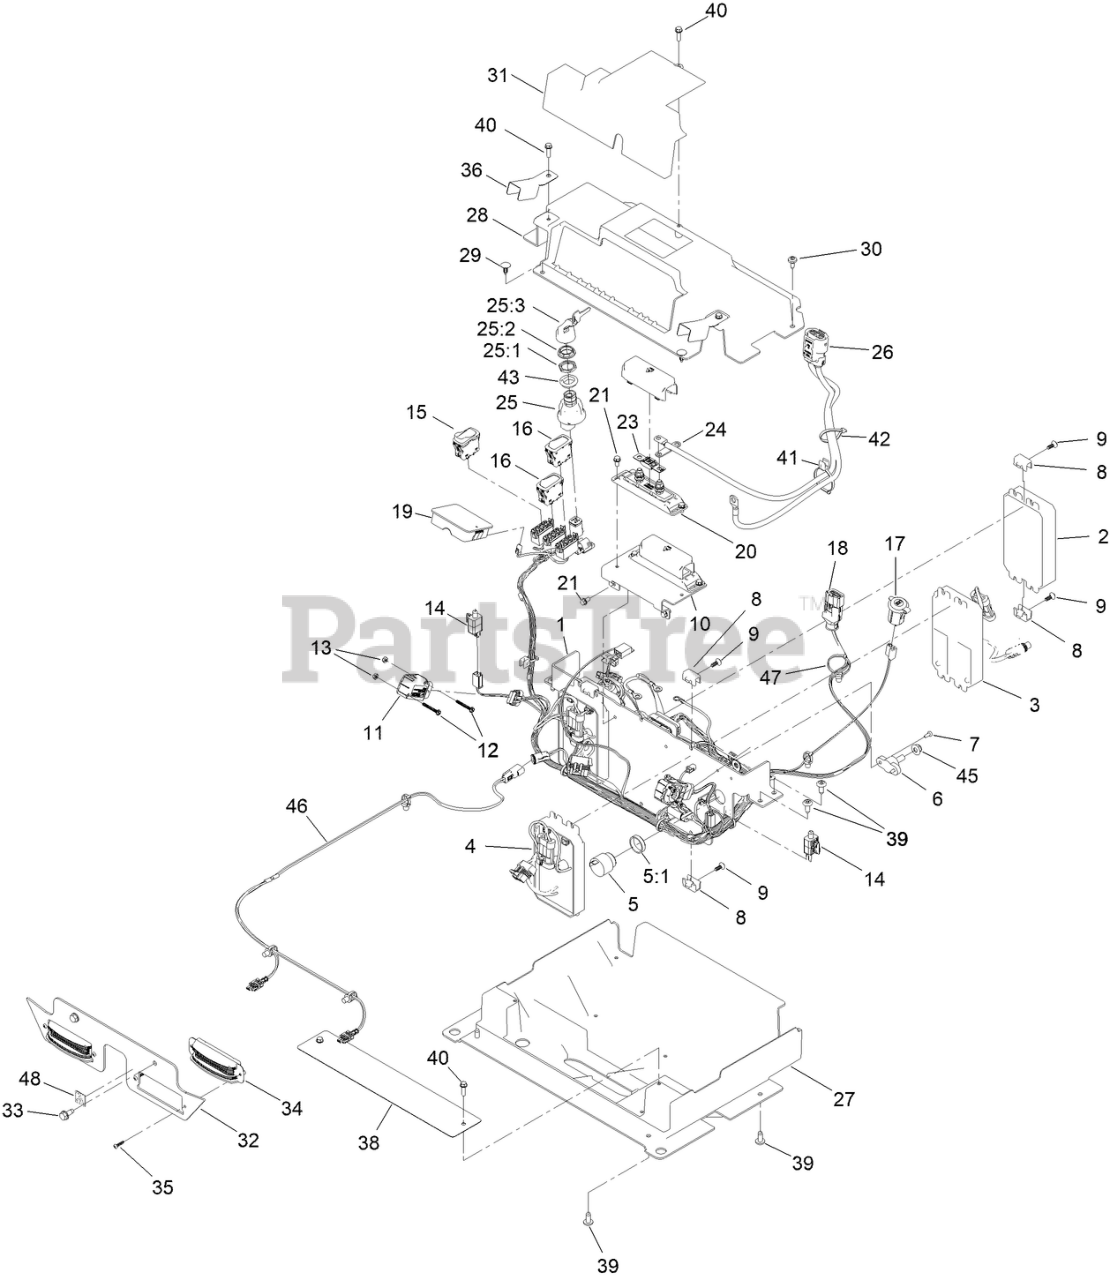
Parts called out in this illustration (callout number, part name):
1	MOUNT-CONTROLLERS
2	CONTROLLER-MASTER
3	CONTROLLER-TRACTION
4	CONTROLLER-DECK
5	AUDIO ALARM ASM
5:1	NUT-PLASTIC, KNURLED
6	BLOCK-JUNCTION
7	SCREW-FORMING, THREAD
8	CLIP-CONTROLLER
9	SCREW-DELTA POINT
10	MOUNT-HOLDER, FUSE
11	SENSOR
12	SCREW-HWH
13	NUT-HEX NI
14	SWITCH
15	SWITCH-ROCKER, ON-NONE-ON
16	SWITCH-ROCKER ON- NONE- ON
17	PORT-POWER, USB
18	HARNESS-WIRE, 2 BLADE
19	DISPLAY
20	HOLDER-FUSE
21	SCREW-HWH
23	FUSE-100 AMP
24	BUSBAR-2, SWITCH
25	SWITCH-IGNITION, SUNS
25:1	NUT-HEX
25:2	NUT-FACE, M22 (PLASTIC)
25:3	SET-KEY, IGNITION
26	HARNESS-WIRE, POWER CABLE
27	COVER-BOTTOM
28	COVER-CONTROLLER
29	PLUG-PLASTIC
30	SCREW-SHOULDER
31	COVER-OUTER
32	MOUNT-HEAD LIGHTS
33	SCREW-HWHTF
34	ASM-LIGHT,LED
35	SCREW-PPH
36	COVER-SENSOR
38	COVER-WIRE
40	SCREW-PLASTITE, HWH
41	CLIP-EDGE
42	TIE-CABLE
43	ADAPTER-SWITCH, KEY
45	NUT-HF, NI
46	HARNESS-WIRE, LED LIGHTS
47	CLIP-TIE
